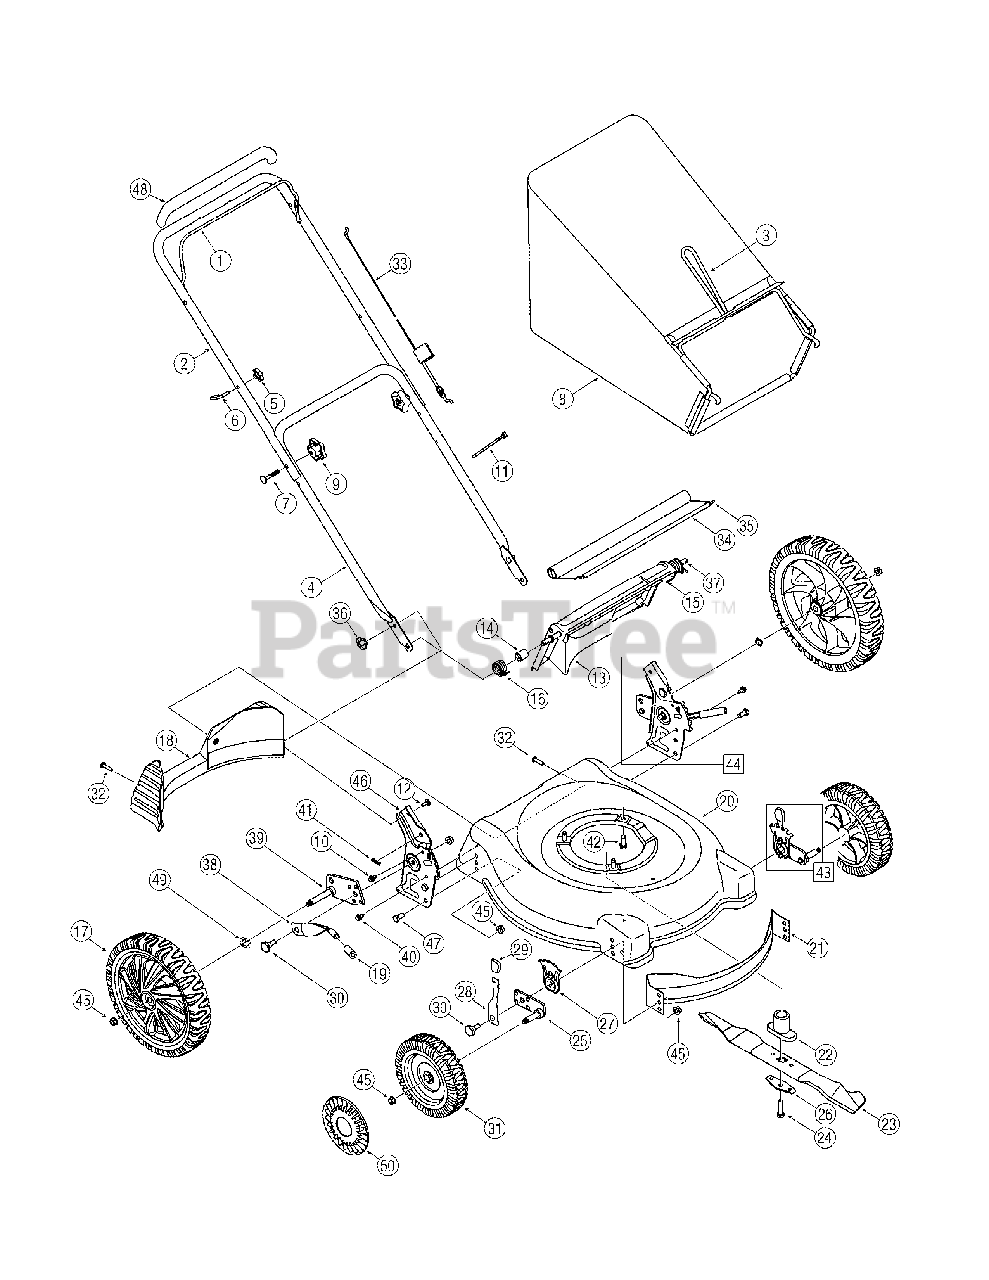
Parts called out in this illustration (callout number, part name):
1	Blade Control Handle
4	Lower Handle
5	Wing Nut
6	Rope Guide
7	Carriage Bolt, 5/16-18 x 2
8	Grass Bag Assembly
9	Star Knob
10	Screw, 1/4-20 x .500
11	Cable Tie
12	Carriage Bolt ,1/4-20
13	Rear Discharge Door
14	Spacer
15	Torsion Spring - LH
16	Torsion Spring - RH
17	Rear Wheel, 12" x 2.125"
18	Rear Baffle
19	Spring Lever Grip
21	Front Baffle
22	Blade Adapter
23	Mulching Blade
24	Hex Screw , 3/8-24 x 2.5
25	Pivot Arm Assembly -RH
25	Pivot Arm Assembly -LH
26	Blade Bell Support
27	Front Adjustment Plate
28	Adjustment Lever Knob
29	Spring Lever
30	Shoulder Screw
31	Front Wheel, 8" x 2.125"
32	Screw, 1/4-15 x 1.250
33	Control Cable - 40.00"
34	Trailshield
35	Trailshield Wire
36	Wing Nut, 1/4-20
37	Rear Door Pivot Rod
38	Spring Lever
39	Pivot Arm Assembly - RH
39	Pivot Arm Assembly - LH
40	AB Screw
41	Hairpin Clip
42	TT Sems Screw, 3/8-16 x 1.0
43	Ht. Adj. Assy. Front - LH
43	Ht. Adj. Assy. Front - RH
44	Rear Handle Bracket Assy - LH
44	Rear Handle Bracket Assy - RH
45	Flange Lock Nut, 3/8-16
46	Handle Bracket Assembly - RH
46	Handle Bracket Assembly - LH
47	Hex Screw, 3/8-16 x 0.75
48	Deluxe Bail Cover
49	Spring Washer
50	Radial Spoke Hubcap
